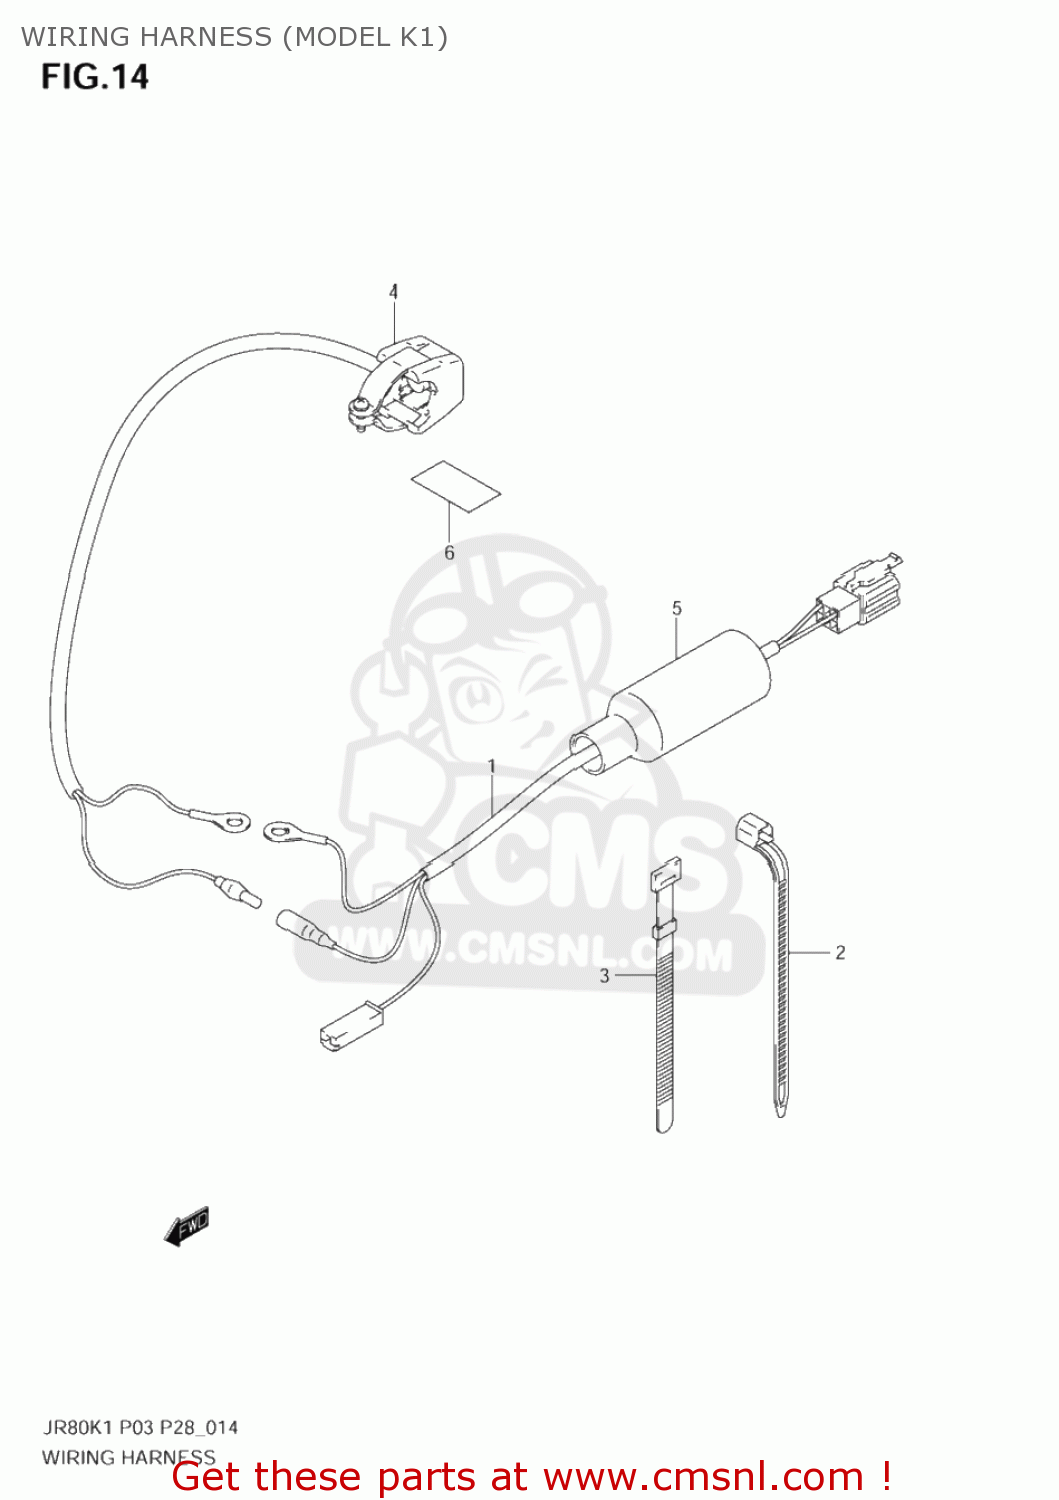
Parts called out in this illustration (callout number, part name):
1	HARNESS,WIRING
2	CLAMP(L:125)
3	CLAMP(L:120)
4	SWITCH ASSY,ENGINE STOP
5	COVER,WIRE
6	LABEL,ENGINE STEP SWITCH
